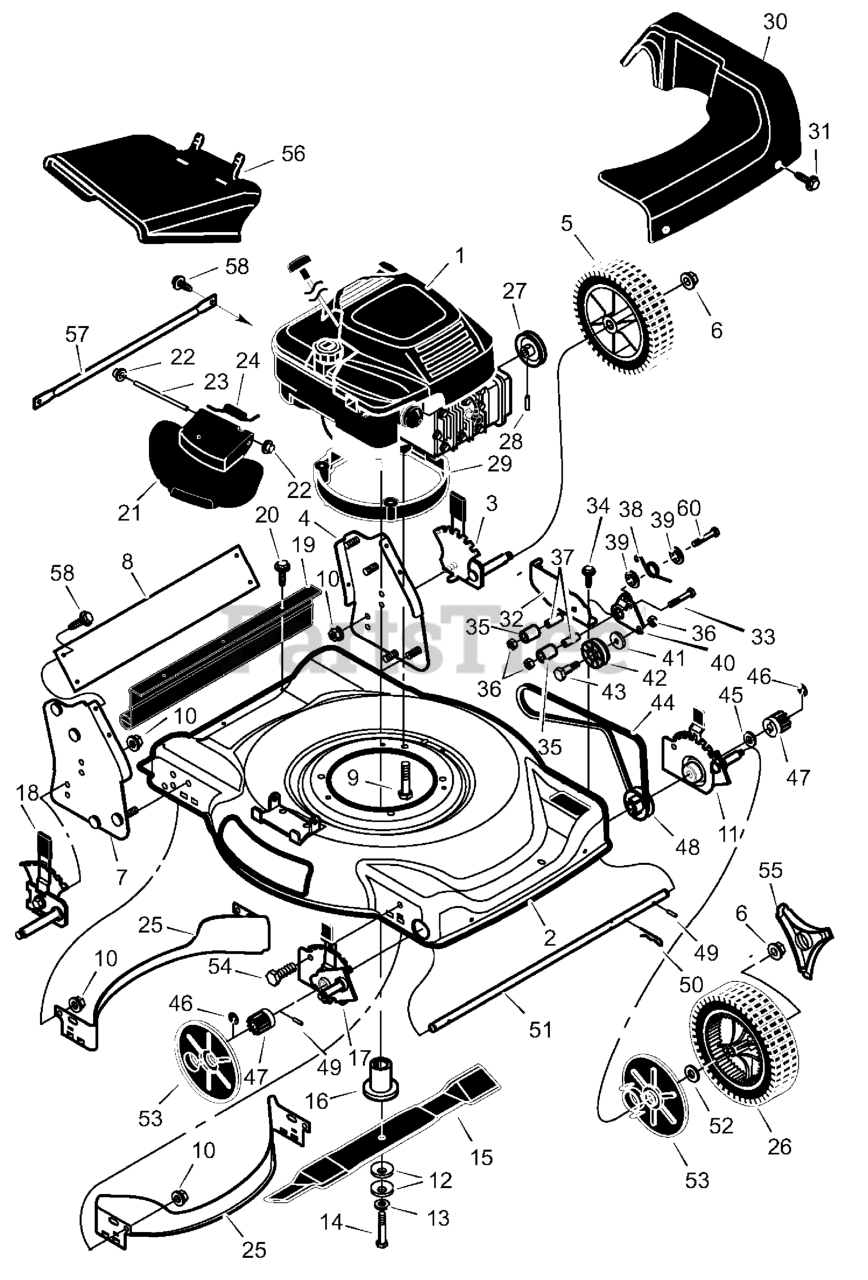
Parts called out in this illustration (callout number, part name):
1	Engine
2	Housing
3	Height Adjuster, Left Rear
4	Bracket, Left Handle
5	Wheel and Tire, Rear
6	Locknut, Flange
7	Bracket, Right Handle
8	Brace, Handle Bracket
9	Bolt, Engine
10	Nut
11	Height Adjuster, Left Front
12	Washer, Belleville
14	Bolt, Hex
16	Adapter, Blade
17	Height Adjuster, Right Front
18	Height Adjuster, Right Rear
19	Guard, Rear
21	Cover, Mulcher
22	Push-On Cap
23	Pin, Pivot
26	Wheel and Tire, Drive
28	Pin, Spring
29	Base, Engine
30	Cover, Belt
32	Bracket, Idler Support
35	Idler, Backside
36	Locknut
37	Bearing
40	Arm, Pivot
42	Pulley, Idler
43	Bolt, Shoulder
46	Ring, Retainer
47	Gear, Pinion
49	Pin, Drive
50	Pin, Hair
52	Washer
53	Cover, Dust
54	Bolt
55	Hub Cap
56	Deflector, Chute
